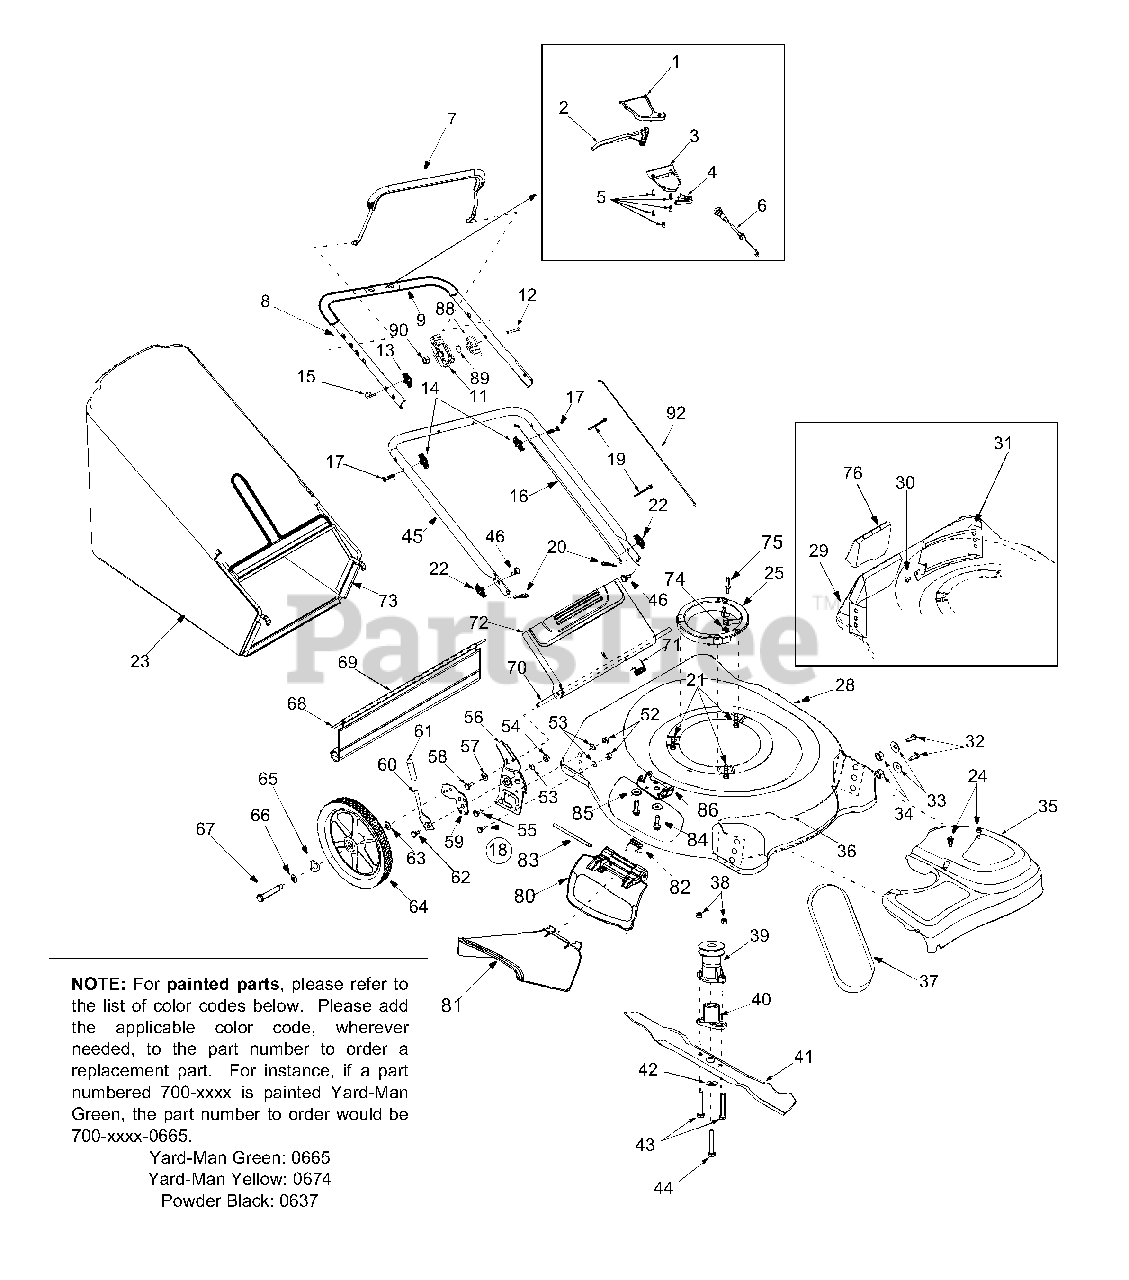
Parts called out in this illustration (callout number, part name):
1	Upper Drive Cover
2	Drive Lever
3	Lower Drive Cover
4	Mounting Cap
5	Screw # 10-16 x .75
6	Drive Cable
9	Foam Grip, 9"
11	Throttle Housing w/Choke
12	Oval C-Sunk Screw 1/4-20 x 1.825
13	Handle Knob
14	Handle Knob
15	Eye Bolt
16	Control Cable, 39"
17	Carriage Bolt 5/16-18 x 2.0
18	RH Bracket Ass'y
19	Cable Tie
20	Cotter Pin
21	Self-Tapping Screw
22	Wing Knob
23	Grass Bag
24	Screw # 12 x .457
25	Engine Spacer
30	Screw AB: 1/4-14: .625
32	Hex Screw 3/8-16 x .75
33	Bell Washer .39 x 1.13 x .062
34	Hex Nut 3/8-16
35	Transmission Cover
38	Hex Nut 1/4-20
39	Drive Pulley
40	Blade Adapter
41	21" Mulching Blade
42	Flat Washer .516 x 1.5 x .134
43	Hex Screw 1/4-20 x 1.50
44	Hex Screw 3/8-24 x 2.50
46	Carriage Bolt, 1/4-20 x .75"
52	Hex Nut 3/8-16
53	Bell Washer .39 I.D. x 1.38 O.D.
54	Hex Flange Lock Nut 3/8-16
55	Hex Scr. w/Washer 1/4-14 x .625
57	Bell Washer .265 x .75 x .062
58	Hex Screw TT 1/4-20 x .500
59	RH Pivot Bar
60	Height Adj. Lever
61	Foam Grip
62	Shoulder Scr .500 Dia. x .434
63	Washer .401 x .870 x .063
64	Wheel, 14 x 2
65	Spring Washer .50 I.D. x 1.0 O.D.
66	Flat Washer .510 x 1.373 x .04
67	Shoulder Screw
68	Wire
69	Rear Trailing Shield
70	Pivot Rod
71	Torsion Spring
74	Hex Nut
75	Screw
80	Mulching Plug (Hinged)
81	Chute Deflector
82	Torsion Spring
83	Hinge Pin
84	Tapp Scr. 1/4-20 x .500
85	Bell Washer .265 x .75 x .062
88	Throttle Lever
89	Curved Spring Washer
90	Hex Lock Nut 1/4-20
92	Throttle Cable
